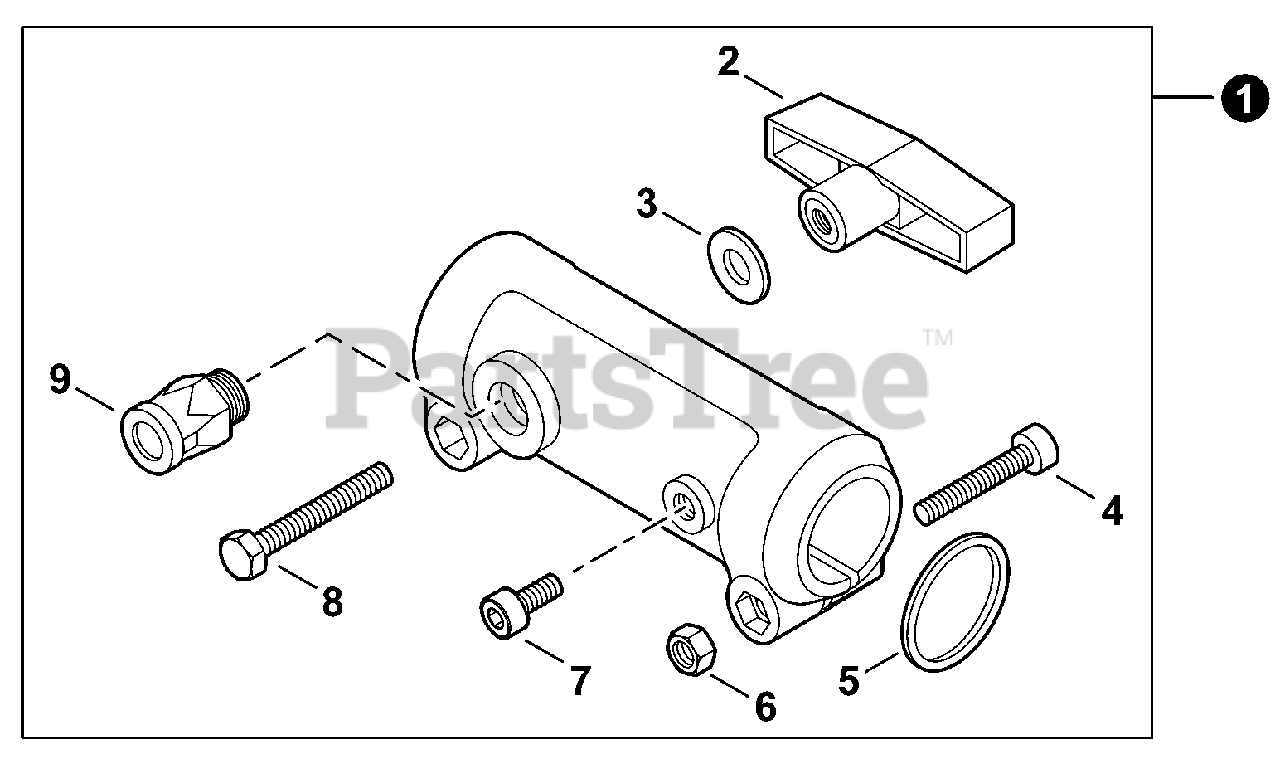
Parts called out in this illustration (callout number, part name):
1	COUPLER ASSY
2	KNOB, FASTENER
3	WASHER 6.6×20×1.6
4	BOLT, TORX 6×25
5	WASHER 18 SPR STEEL
7	BOLT, TORX 5×10
8	BOLT 6×40
9	LATCH ASSY
